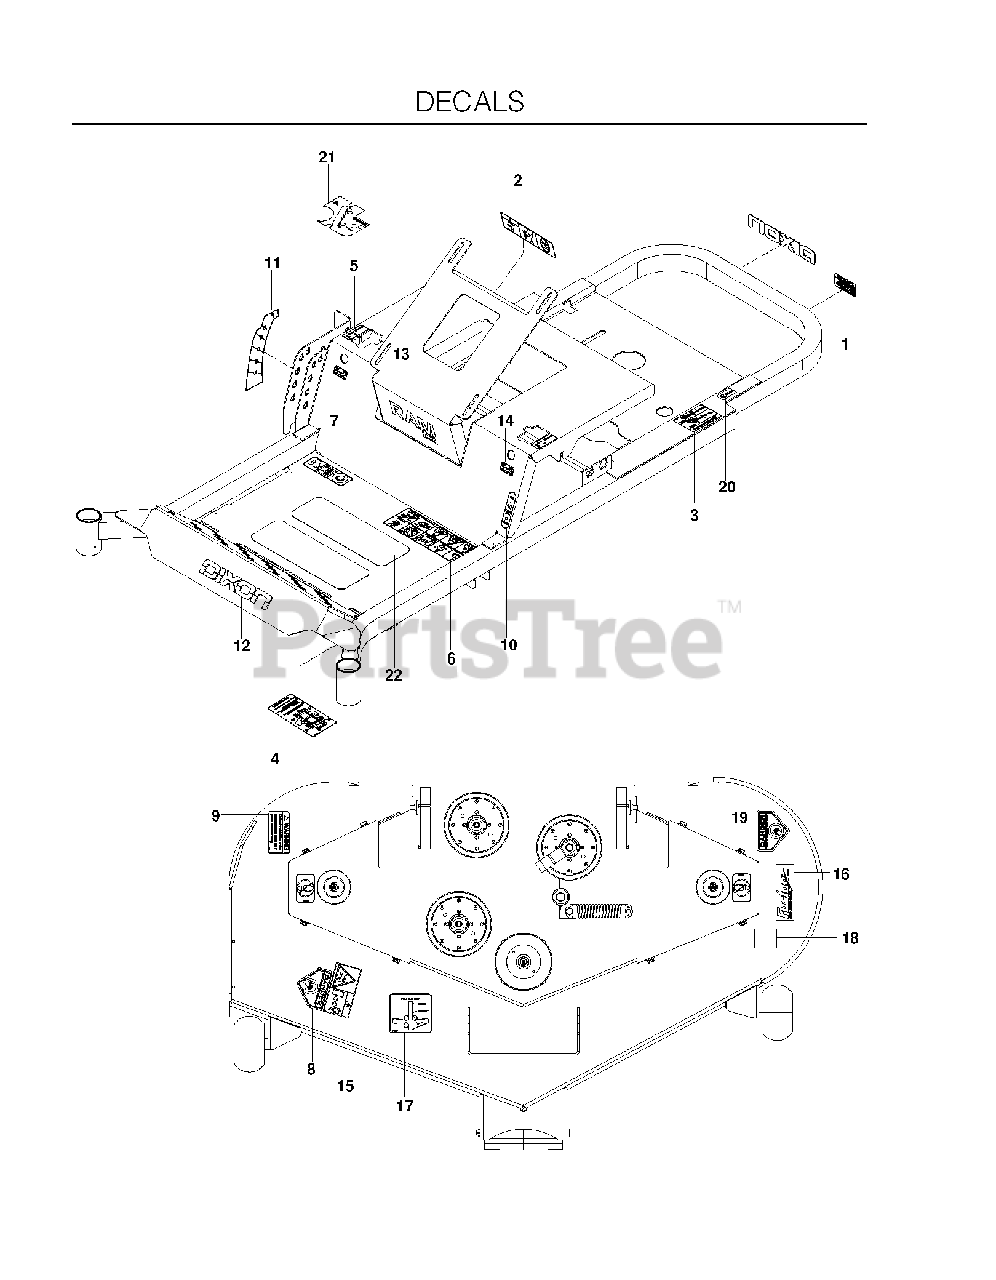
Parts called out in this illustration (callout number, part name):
1	DECAL, PROP. 65
2	DECAL, BATTERY
3	DECAL, DO NOT MOUNT
4	DECAL, SERVICE
5	DECAL, MOTION CONTROL
6	DECAL, SAFETY WARNING
8	DECAL, CPSC
10	DECAL, PARK BRAKE
11	DECAL, HEIGHT
13	DECAL, RAM ZTR, 2008
14	DECAL, TRACKING
15	DECAL, EURO SEVERING
16	DECAL, FUSION
17	DECAL, BELT ROUTING
18	DECAL, 48
19	DECAL, NO STEP
20	DECAL, ECM, AUSTRALIA
21	DECAL, CONTROLS PANEL, DIX
22	ANTI-SKID PAD
